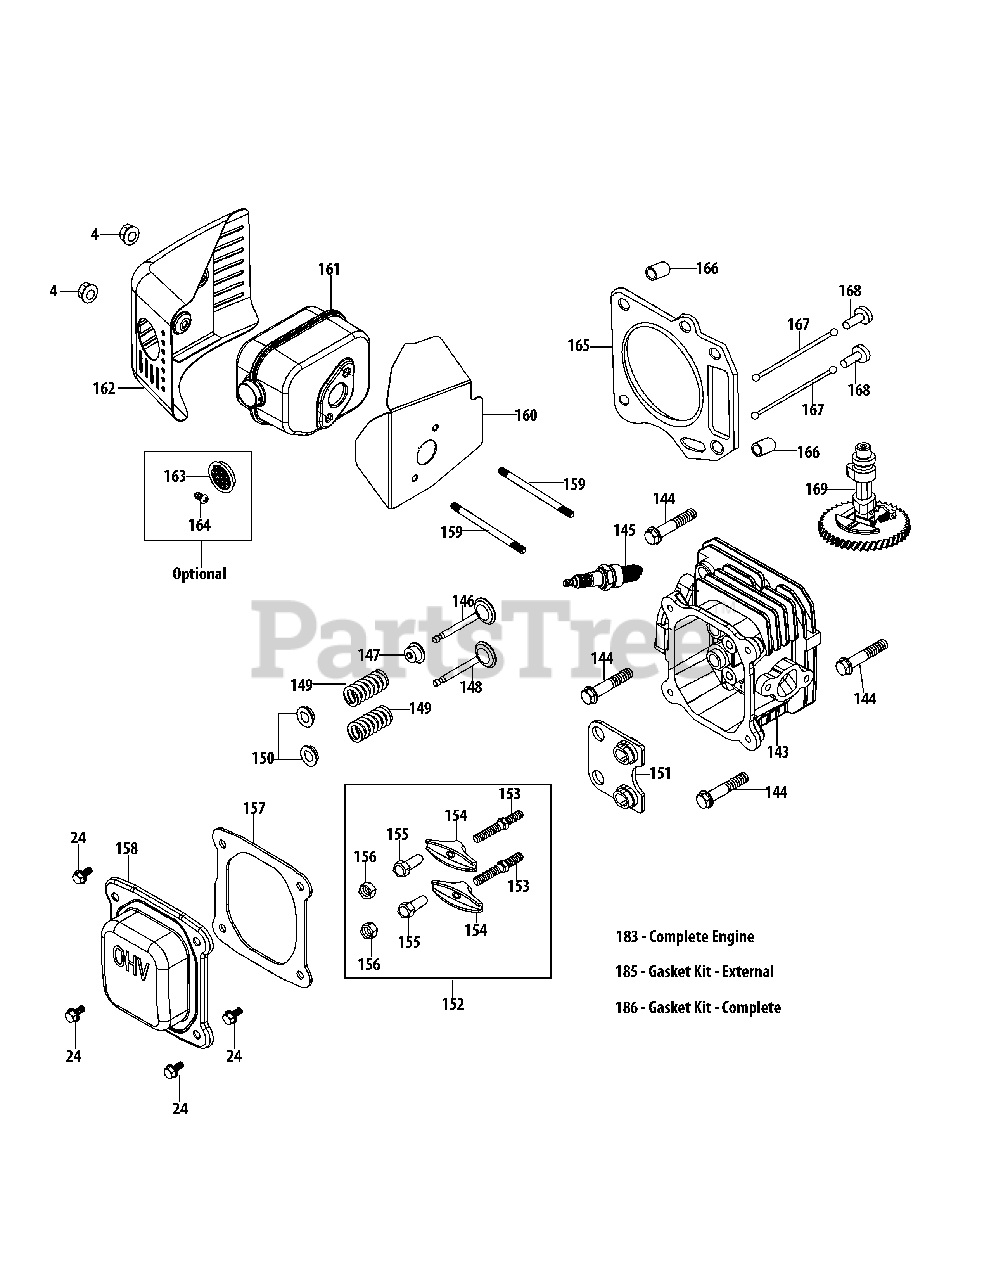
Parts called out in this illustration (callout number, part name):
4	Nut M6X10Mm Starter/Carb/Muff
24	Bolt M6X14 Multi-Purpose
143	Cylinder Head Svc Kit
143	Cylinder Head
144	Bolt M8X54 Cylinder Head
145	Spark Plug
146	Valve Kit
147	Intake Valve Seal
148	Valve Kit
149	Valve Spring
150	Valve Spring Retainer
151	Push Rod Guide
152	Rocker Arm Assembly
153	Rocker Arm Stud
154	Rocker Arm
155	Fulcrum Nut
156	Jam Nut
157	Valve Cover Gasket
158	Valve Cover
159	Muffler Stud M6X95
159	Muffler Stud Ass'Y
160	Muffler Gasket
161	Muffler Assembly
162	Muffler Shield
163	Spark Arrestor
164	Spark Arrestor Screw
165	Cylinder Head Gasket
166	Cylinder Head Dowel Pin 10×16
167	Push Rod Kit
168	Tappet
169	Camshaft Assembly
183	Complete Engine
185	Gasket Kit - External
186	Gasket Kit - Complete
